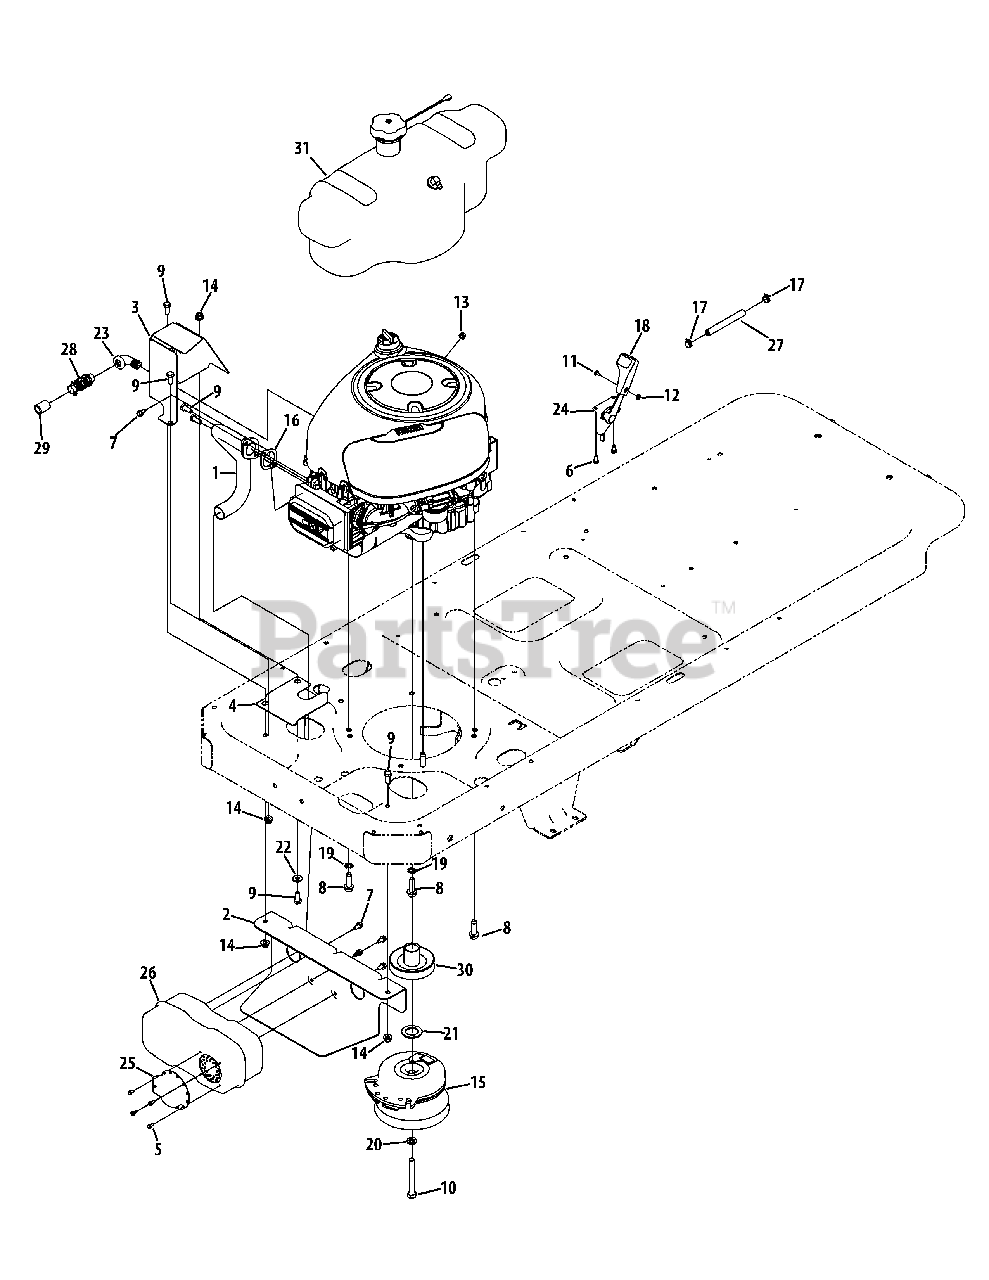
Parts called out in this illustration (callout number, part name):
1	Exhaust Tube Assembly
2	Muffler Mount Bracket
3	Muffler Heat Shield
4	Heat Shield
5	Hex Washer Screw, #8-18 x .500
6	Screw, 1/4-14 x .625
7	Hex Washer Screw, 1/4-20 x .500
8	Hex Washer Screw, 3/8-16 x 1.250
9	Hex Screw, 5/16-18 x .75
10	Hex Screw, 7/16-20 x 3.25
11	Machine Screw, #8-32 x .375
12	Hex Nut, #8-32
13	Sems Nut, 1/4-20
14	Flange Lock Nut, 5/16-18
15	Electric PTO Clutch
16	Exhaust Gasket
17	Hose Clamp, .490
18	Throttle Control Knob
19	Lock Washer, 3/8
20	Lock Washer, 7/16
21	Flat Washer, 1.031 x 1.620 x .095
22	Flat Washer, .344 x .750 x .120
23	Elbow Fitting, 3/8
24	Throttle/Choke Control Cable
25	Muffler Deflector
26	Single Inlet Muffler
27	Low Permeation Fuel Hose
28	Oil Drain
29	Oil Drain Extension Hose
30	Engine Pulley
31	Fuel Tank Assembly
31	Fuel Tank Bushing
31	Rubber Grommet
31	Fuel Pick-Up Fitting
31	Fuel Cap
31	Rollover Valve
